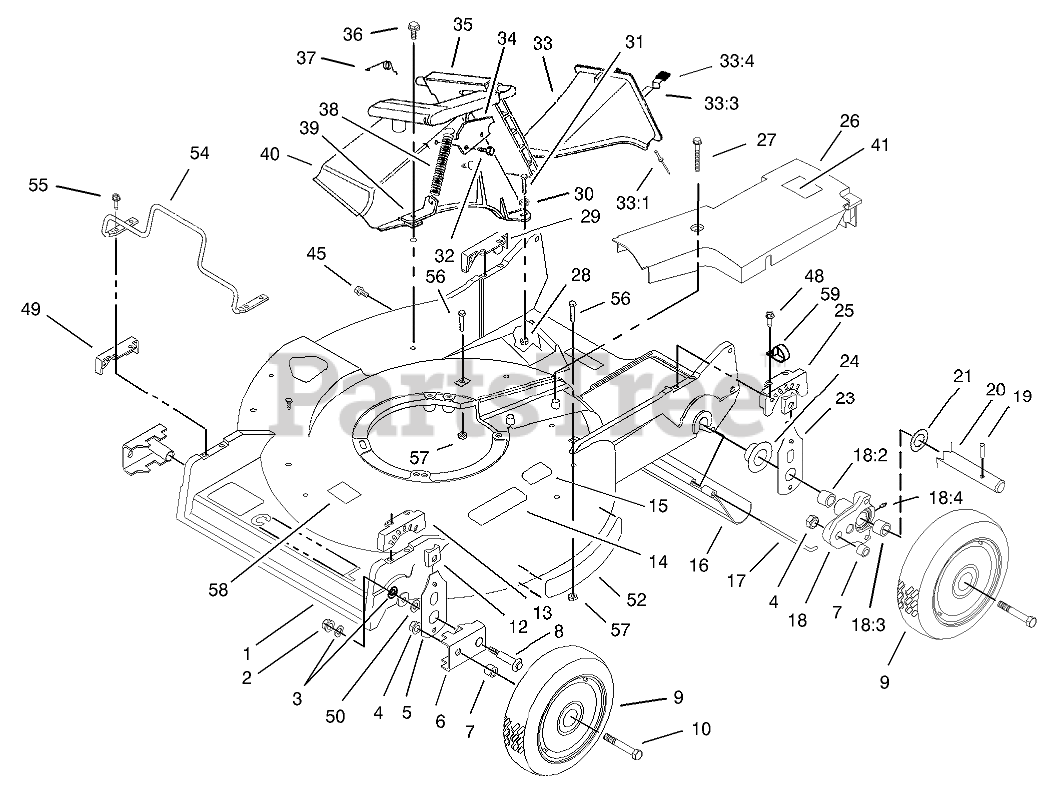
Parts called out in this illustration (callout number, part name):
1	HOUSING ASM
2	NUT-LOCK
3	WASHER
4	NUT-LOCK, CONE
5	FRONT SPRING ARM ASM
6	ARM-PIVOT, FRONT
7	SPACER-WHEEL
8	BOLT-WHEEL
9	Wheel and Tire ASM
10	SCREW-HH
12	KNOB-ARM
13	QUADRANT-FRONT, LH
14	Decal-Warning
15	DECAL-STD, SAFETY
16	SHIELD-TRAILING
17	ROD-SHIELD
18	PIVOT ARM ASM
18:2	FITTING-GREASE
18:3	BUSHING
18:4	BUSHING
19	PIN-SPIROL
20	SHAFT-AXLE, REAR
21	WASHER-PLAIN
23	REAR SPRING ARM ASM
24	CAP-END
25	QUADRANT-REAR, LH
26	COVER-BELT
27	SCREW-HHFTF
28	NUT-LOCK, NI
29	QUADRANT-REAR, RH
30	WASHER-FLAT
31	SCREW-HH
32	SCREW-PLASTITE
33	DISCHARGE PLUG ASM
33:1	RIVET-HEAD, FLAT
33:3	LATCH-PLUG, DISCHARGE
33:4	GRIP-LATCH
34	LATCH-PLATE
35	DISCHARGE DOOR ASM
36	SCREW-HWH
37	RETAINER-DOOR
38	SPRING-DOOR
39	BRACKET-SPRING
40	TUNNEL-DISCHARGE
41	LABEL-GREASE, HP
45	SCREW AND WASHER ASM
48	SCREW-HWHTF
49	QUADRANT-FRONT, RH
50	WASHER-THRUST
54	GUARD-ENGINE
55	SCREW-HWHTF
56	SCREW-HH
57	NUT-LOCK, NI
58	DECAL-BLADE
59	CLIP-CLOSED, INSULATED
